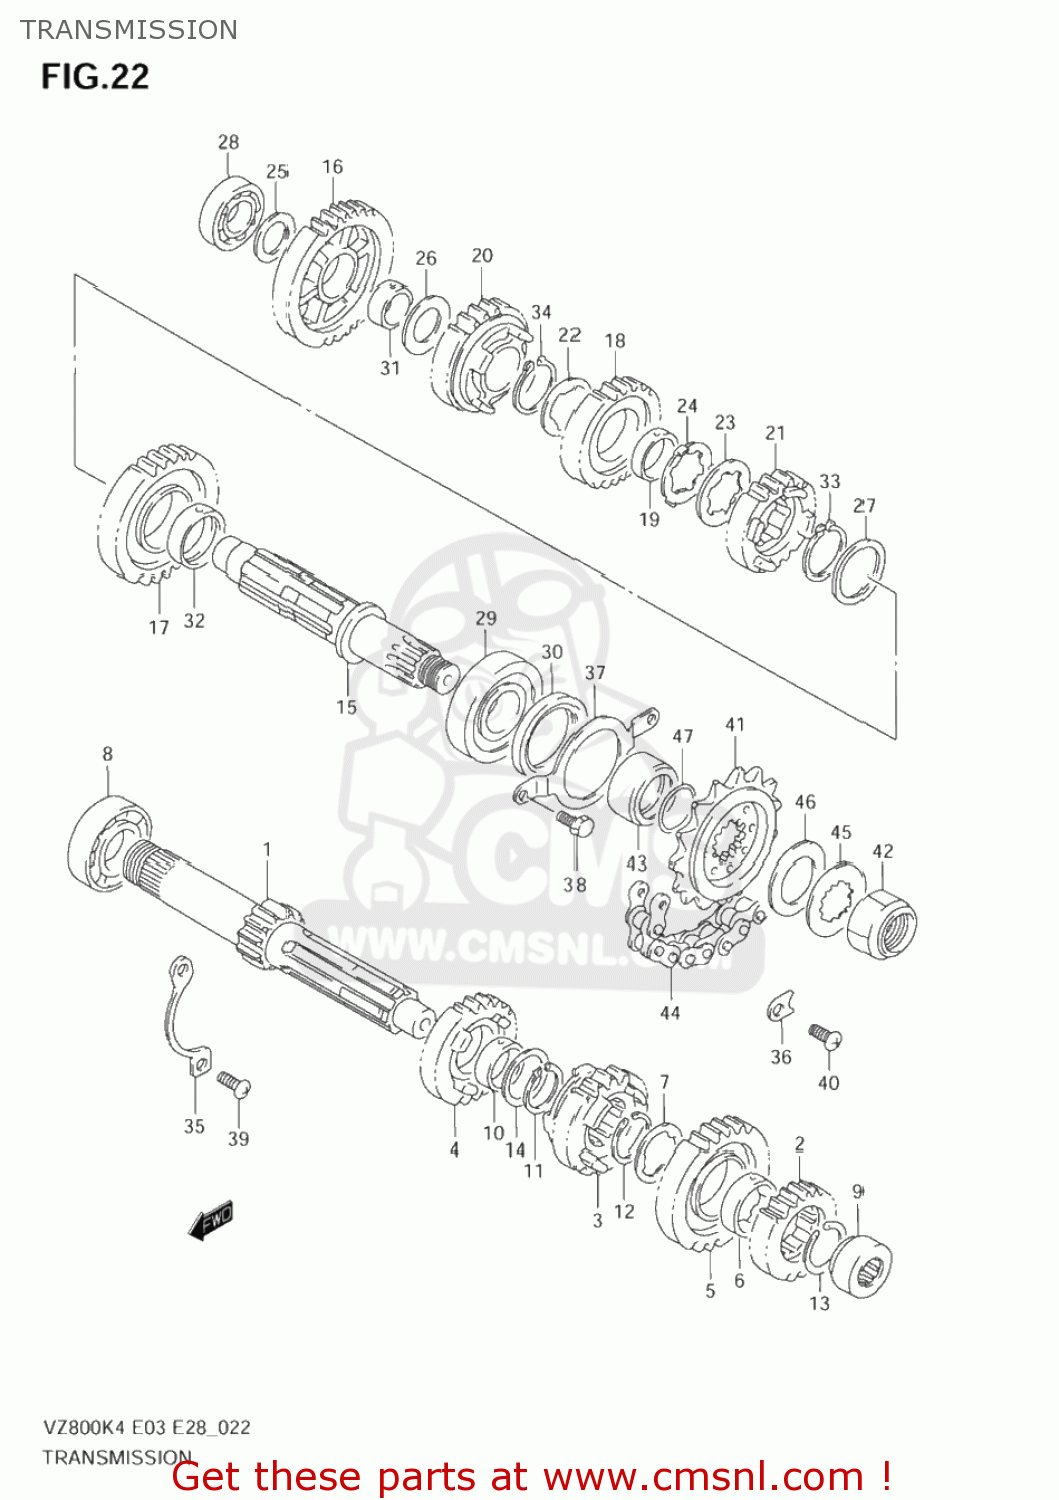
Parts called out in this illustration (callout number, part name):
1	SHAFT,COUNTER
2	GEAR,2ND DRIVE(NT:19)
3	GEAR,3RD DRIVE
4	GEAR,4TH DRIVE(NT:23)
5	GEAR,5TH DRIVE(NT:25)
6	BUSH,6TH DRIVE GEAR
7	WASHER,LOCK
8	BEARING(25X62X17)
9	BEARING(20X33X16)
10	BUSH
11	RING,SNAP
12	RING,SNAP
13	CIRCLIP
14	WASHER
15	SHAFT,DRIVE
16	GEAR,1ST DRIVEN(NT:32)
17	GEAR,2ND DRIVEN(NT:30)
18	GEAR,3RD DRIVEN(NT:24)
19	BUSH
20	GEAR,4TH DRIVEN(NT:22)
21	GEAR,5TH DRIVEN(NT:20)
22	WASHER,LOCK
23	WASHER,LOCK
24	WASHER
25	SHIM(20X32X1)
26	SHIM(22X34X1)
27	SHIM(28X36X1)
28	BEARING(20X42X12)
29	BEARING(25X62X17)
30	SEAL,OIL(36X50X6)
31	BUSH
32	BUSH(28X32X11)
33	CIRCLIP
34	CIRCLIP
35	RETAINER,CNTR SHAFT BEARING
36	RETAINER
37	RETAINER,DRIVE SHAFT OIL SEAL
38	BOLT
39	SCREW
40	SCREW
41	SPROCKET,ENGINE(NT:15)
42	NUT,ENGINE SPROCKET
43	SPACER,FR PULLEY
44	CHAIN(DID50VA2,116L)
45	WASHER,LOCK
46	WASHER(25.2X42X3.2)
47	O RING(D:2.4,ID:23.7)
